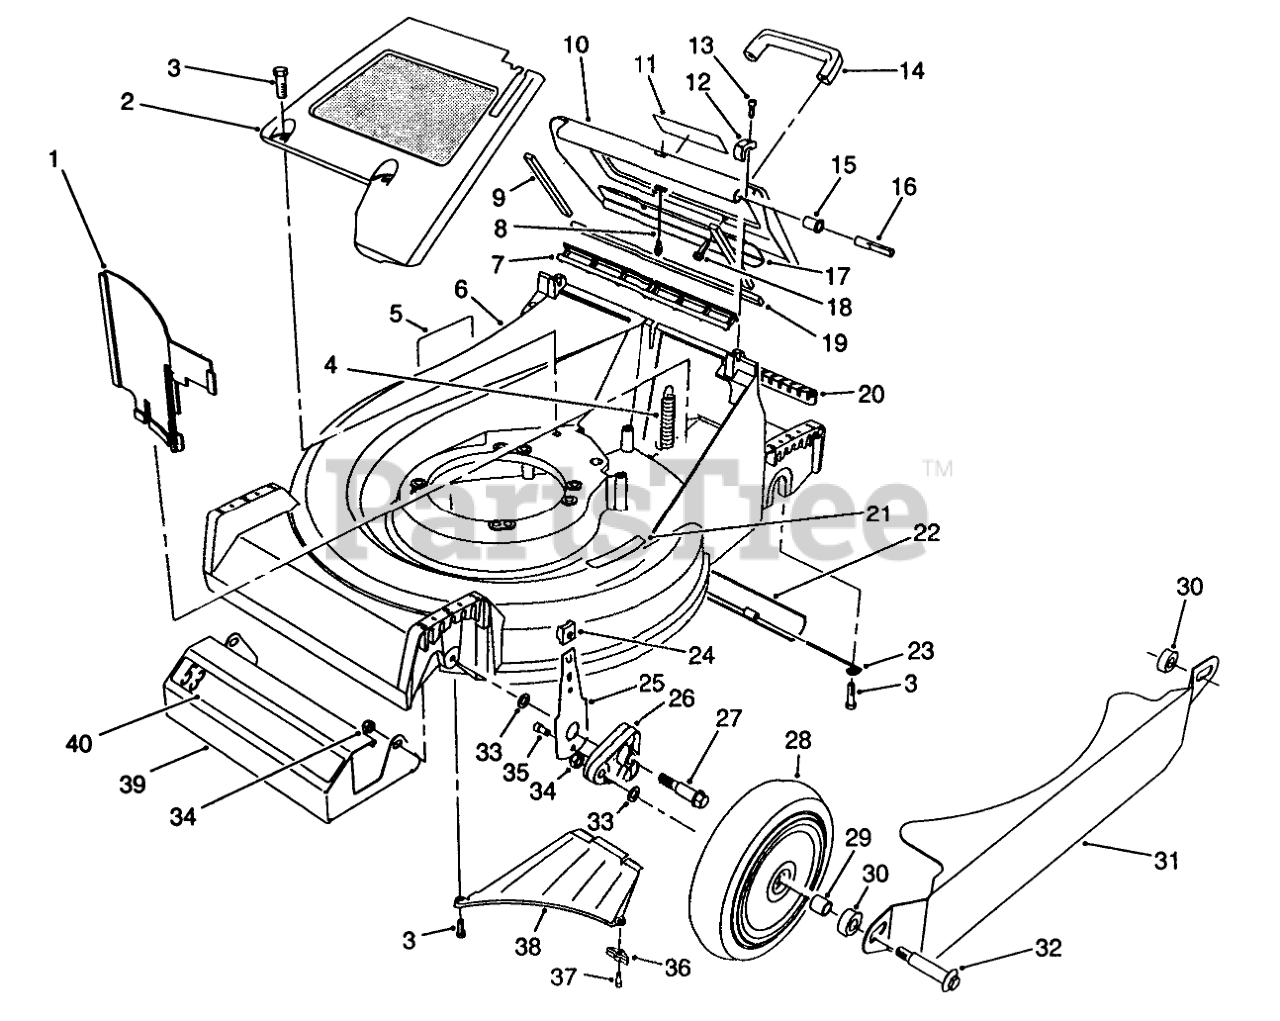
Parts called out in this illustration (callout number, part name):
1	PANEL-VERTICAL
2	PaneI-Screen
3	SCREW-HWHTF
4	EXTENSION-SPRING
5	Decal Danger
6	Housing-53cm (Incl. Ref. #5 & 21)
7	DOOR SEAL
8	DOOR CABLE
9	DOOR SIDE SEAL
10	Door-Discharge (Incl. Ref. #9, 11 & 19)
11	Decal-Warning
12	HINGE CLAMP
13	SCREW-HSH
14	HANDLE-DOOR
15	DOOR BUSHING
16	HINGE PIN
17	DOOR - BRACE
18	SCREW-HWH
19	DOOR END SEAL
20	ACCESS COVER
21	DECAL - STEP PAD INT'L
22	TRAILING SHIELD
23	LH SHIELD HANGER
24	KNOB-ARM
25	FRONT SPRING ARM ASM
26	ARM-PIVOT, FRONT
27	BOLT-SHOULDER
28	Wheel & Tire Assembly (Incl. Ref. #29)
29	BUSHING
30	Spacer
31	Shield-Side (L.H.)
32	BOLT-WHEEL
33	WASHER
34	Nut
35	SCREW-HSH, THREAD FORMING
36	Bracket-Discharge
37	SCREW-HWHTF
38	Ramp Discharge
39	FRONT SHIELD
40	DECAL - 53 CM
